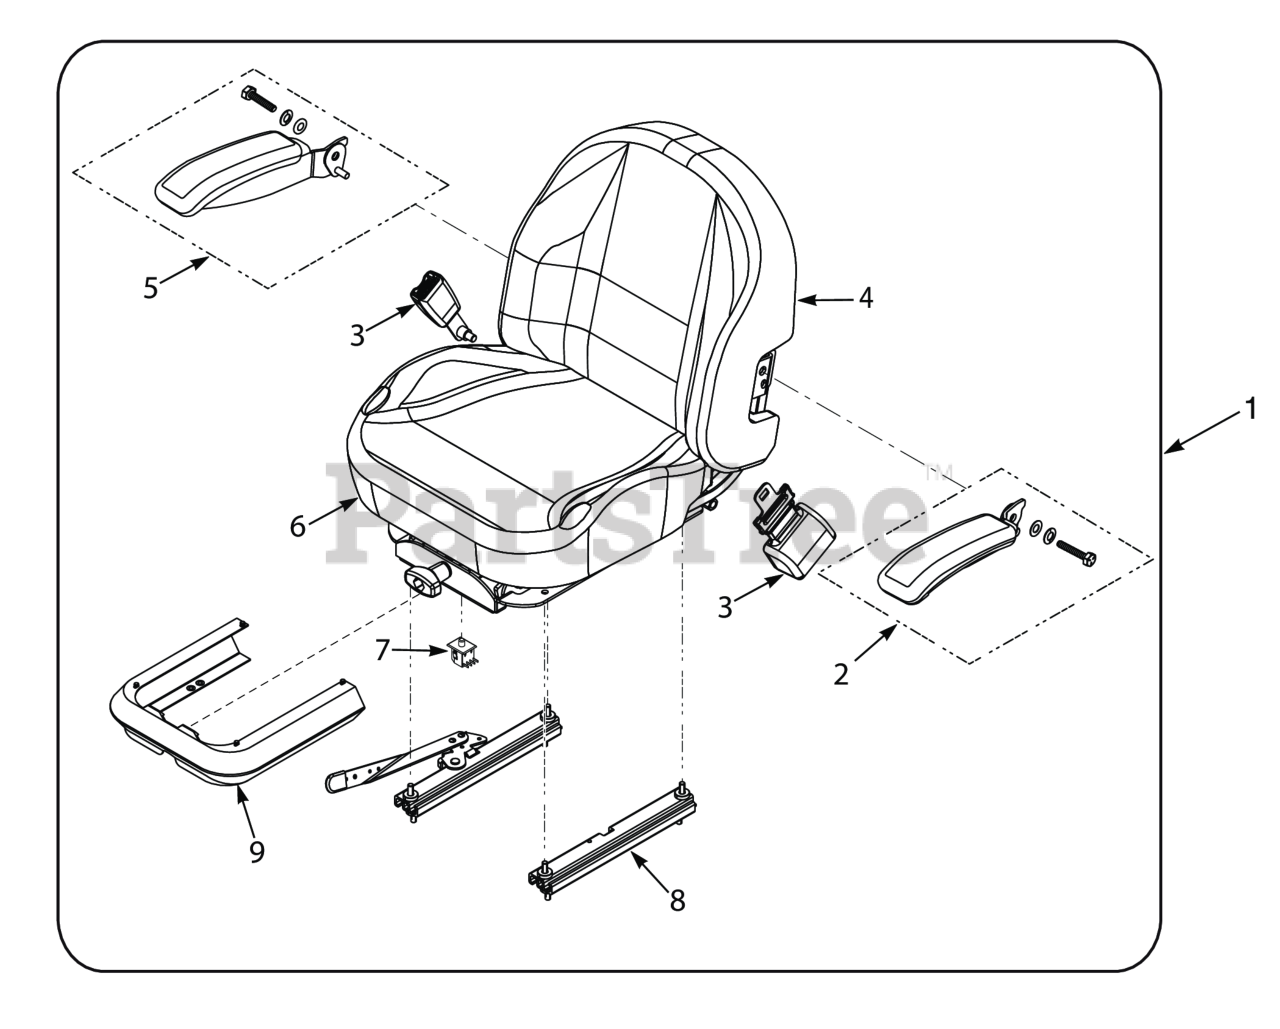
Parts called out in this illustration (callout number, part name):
1	Seat Assembly
2	Armrest Kit, LH
3	Seatbelt Kit
4	Back Cover
5	Armrest Kit, RH
6	Cushion Cover
7	Switch, Double Pole - Plunger
8	Track Set
9	Bellows, Seat
